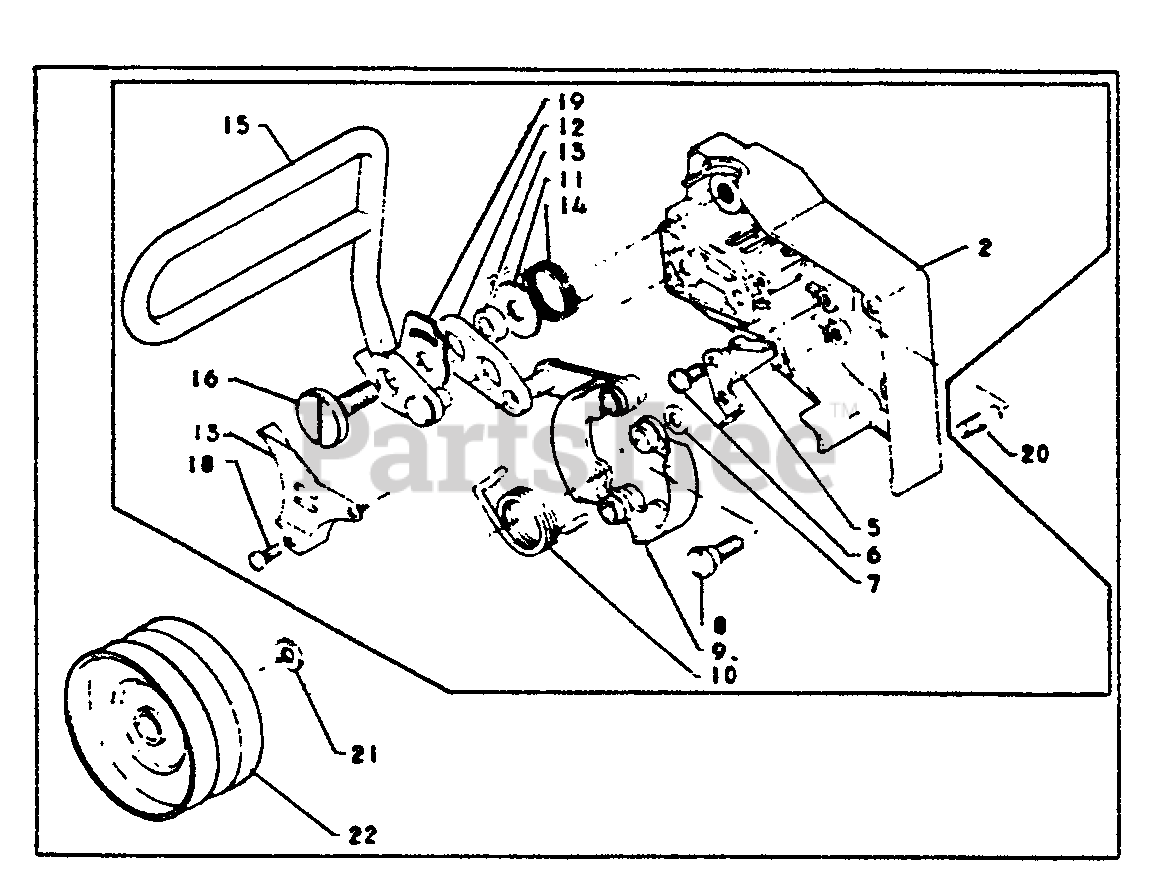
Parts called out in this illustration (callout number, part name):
2	COVER, GUIDE BAR
5	GUIDE, BRAKE SHOE
6	SCREW 5×8
7	WASHER 6.5×11.5×0.8
9	SHOE, BRAKE
10	SPRING
11	SPACER
12	CONNECTOR
13	SPACER
14	SPRING, RETURN
15	HANDLE, BRAKE
17	SEAL
18	SCREW 4×10
19	WASHER
20	PIN, DOWEL
21	WASHER
22	DRUM, CLUTCH
22	CHAIN BRAKE ASSY
